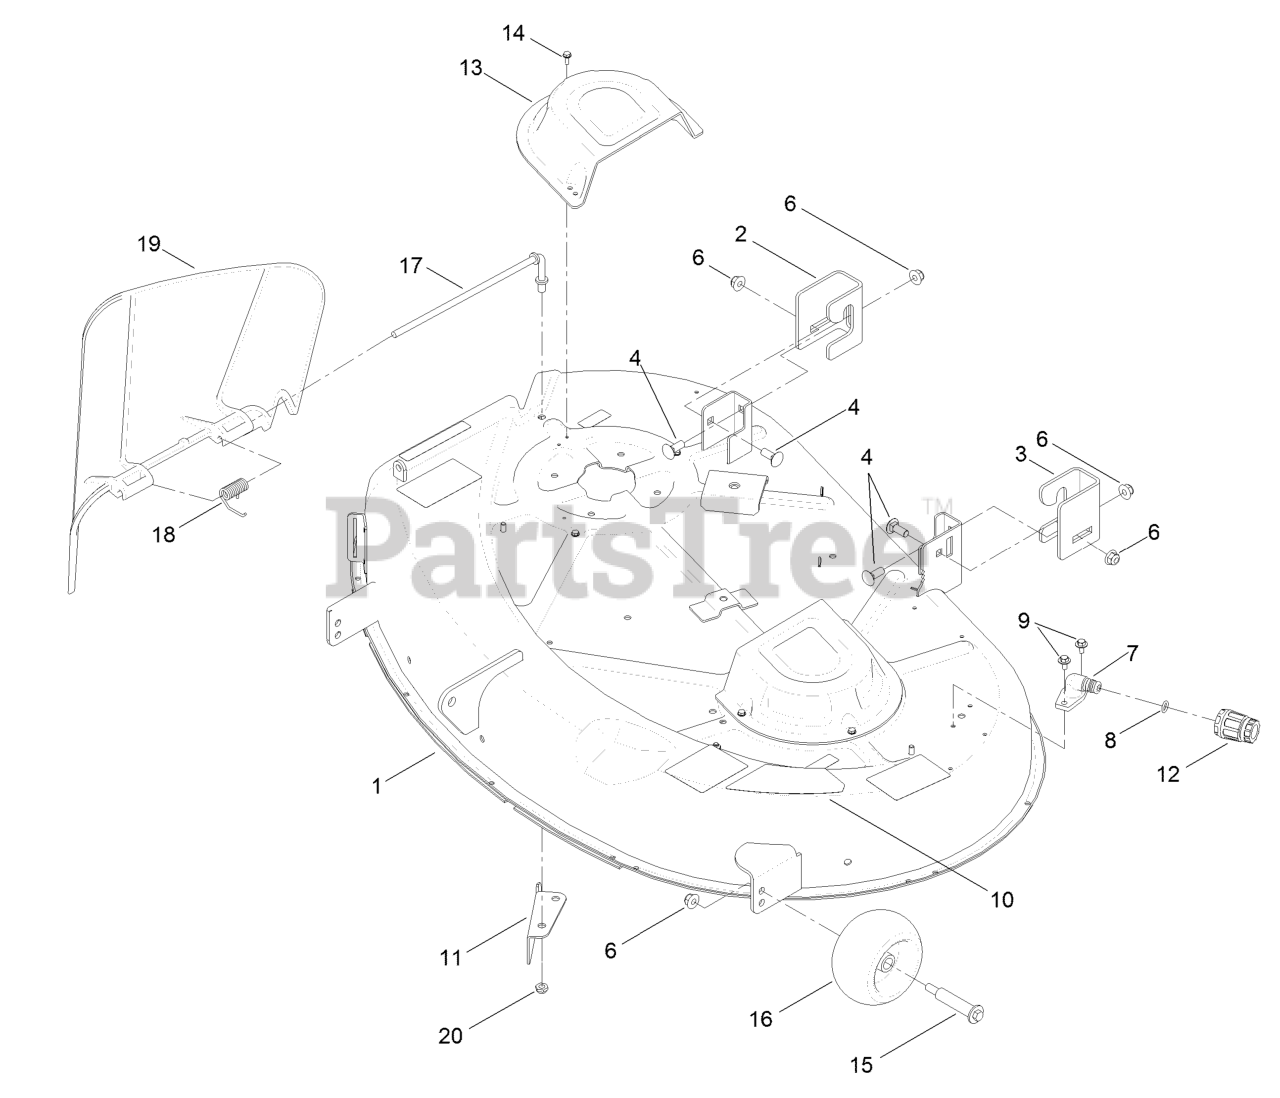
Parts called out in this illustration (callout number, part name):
1	42 INCH DECK AND DECAL AS
3	BRACKET-HANGER, LH
4	BOLT-CARR
6	NUT-HF, NI
9	SCREW-HHFTF
11	BAFFLE-CUTOFF
12	CONNECTOR-HOSE
13	COVER-BELT
14	SCREW-TAPTITE
15	BOLT-SHOULDER
16	ROLLER-SCALP, ANTI
17	ROD-PIVOT
18	SPRING-TORSION
19	DEFLECTOR
